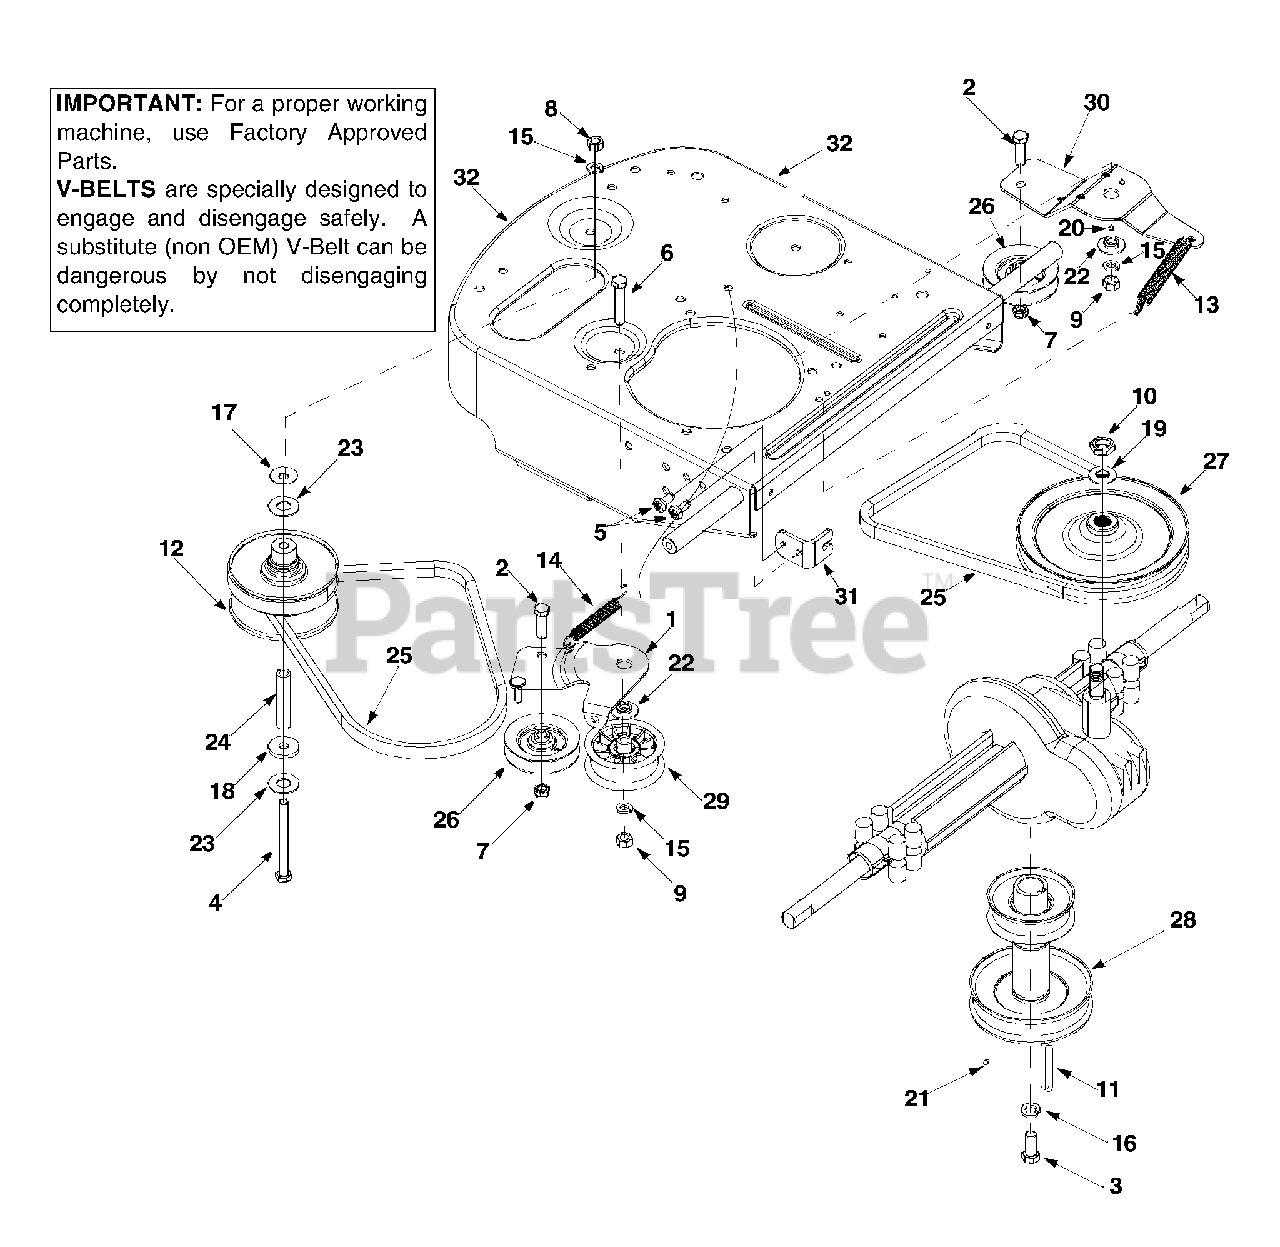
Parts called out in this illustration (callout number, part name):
1	Idler Bracket Assembly
2	Hex Screw
3	Hex Screw 7/16-20 x 1.0"
4	Hex Screw 3/8-24 x 3.75"
6	Hex Screw 3/8-16 x 2.0"
7	Jam Lock Nut
8	Hex Nut 3/8-24
9	Hex Nut 3/8-16
10	Jam Nut 9/16-18
11	Sq. Key
12	Variable Speed Pulley Assembly
13	Extension Spring
14	Extension Spring
17	Bell Washer
19	Beleville Washer
20	Grease
21	Grease
22	Shoulder Spacer
23	Thrust Bearing
25	V-Belt
26	Idler Pulley
27	Transmission Pulley
28	Engine Pulley
29	Flat Idler Pulley
30	Idler Bracket: Variable Speed
